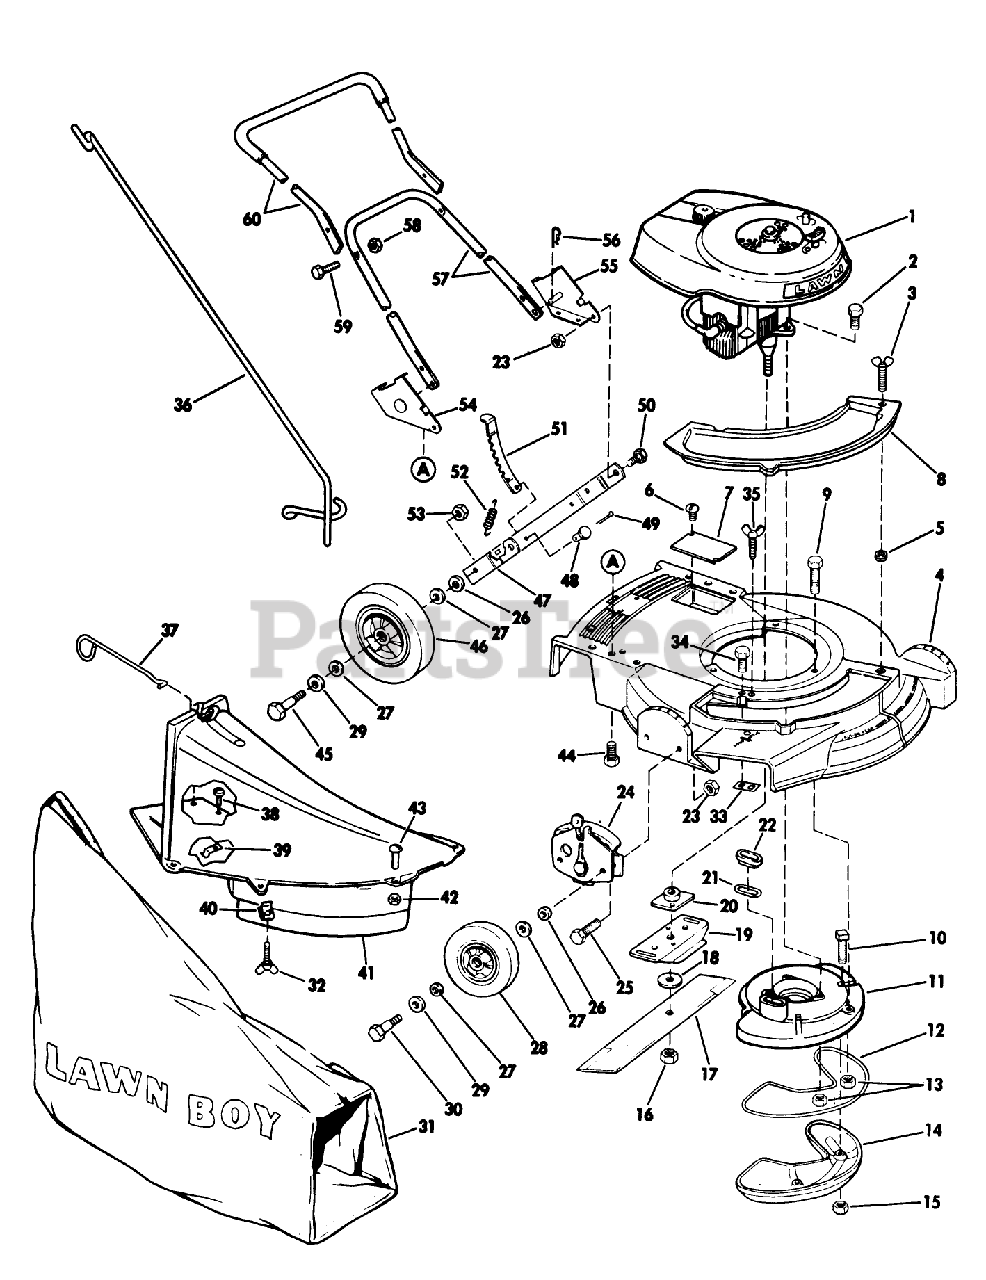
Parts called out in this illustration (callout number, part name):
15	LOCKNUT E
16	NUT-BLADE
20	PLATE AND COLLAR ASM
21	GASKET S
26	WASHER WROUGHT
30	BOLT WHEEL
31	89802 LB WHOLE GOODS
40	SPEED NUT ARDEN
41	Chute Skirt Assembly (Includes Hardware)
42	NUT S
50	BOLT-SHOULDER
52	SPRING N.A.S
53	LOCKNUT
56	HAIR PIN
